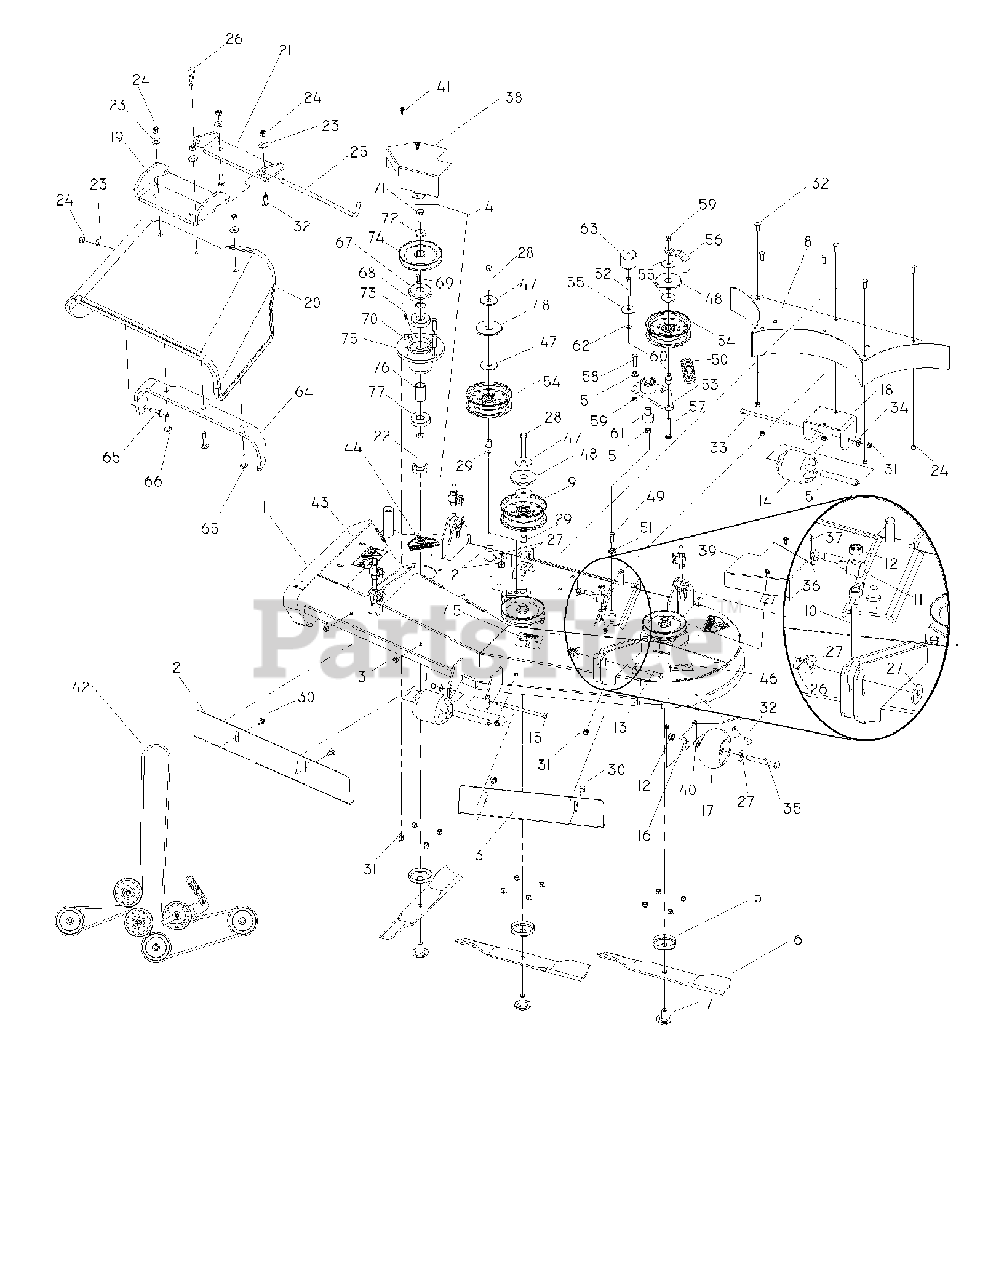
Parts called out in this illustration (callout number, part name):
1	DECK W/DECAL 52 KODIAK
2	BLOW-BY BAFFLE 52` LH
3	BLOW-BY BAFFLE 52` RH
4	SPINDLE ASM.
5	TRASH GUARD
6	BLD 52HFS HI LIFT FUS
7	BLADE BOLT/WASHER
8	W-BAFFLE WLDT.
9	IDLER PULLEY (TALL)
10	BOLT, EYE
12	NUT 1/2-13 HEX NYLOC ZD
13	CLEVIS PIN 1/2X1-3/4LG
14	ROLLER 3-3/4 DIA. X 4-1
15	BUSHING
16	BRACKET
17	GAUGE WHEEL
18	REAR CENTER ROLLER BKT 52 CLK
19	PIVOT BRKT RUBBER CHUTE
20	CHUTE, RUBBER DISCHARGE 52"
21	PIVOT BRACKET - DECK
22	SHAFT SHORT
23	WASHER 5/16 FLAT
24	NUT 5/16 NYLOC
25	DEFLECTOR PIN
26	PIN, COTTER 1 3/4
27	WASH USS FLAT 1/2
28	SCREW, 1/2C X 3 HEX CAP
29	SPACER - IDLER
30	RHSNB 3/8-16 X 3/4 GR5 ZD
31	NUT 3/8-16 NYLOC
32	RHSSNB 5/16C X 1.0
33	3/8-16 X 6-1/2 HHB GR8
34	WASHER 3/8 FLAT
35	HCS 1/2-13 X 4 GR 5 ZD
36	WASHER 1/2" FLAT
37	PIN COTTER 1/8 X 1 ZD
38	PULLEY GUARD RH BLACK
39	PULLEY GUARD 52 LH BLACK
40	NUT HEX 1/2
41	SCREW, TAP & DR #12-14 X 3/4
42	BELT-DECK, 52
43	DECAL, EURO SEVERING
44	DECAL, CPSC
45	DECAL, BELT ROUTING (18656)
46	DECAL, 52"
47	ISOLATOR WASHER
48	TOP DUST CAP
49	HCS 3/8C X 1
50	DECK SPRING
51	NUT 3/8C WHIZ
52	HCS 3/8C X 2 1/2
53	ARM-IDLER W/BRG
54	IDLER PULLEY
55	WASHER, 3/8 SPEC
56	GUIDE, BELT
57	RHSNB 3/8-16 X 2.75
58	HCS 3/8-16 X 1-1/2
59	NUT 3/8-16 HEX JAM
60	BUSHING, IDLER
61	PIVOT, BEARING
62	WASHER 3/8 SAE FLAT
63	CAP, VINYL
64	BRACKET, REINF - CHUTE
65	BOLT, CARRIAGE 5/16X1-1/4
66	RHSNB 5/16-18 X 1-1/2 GR 5 ZD
67	TRASH GUARD
68	HUB PULLEY SPACER
69	KEY - 1/4 X .88
70	HCS 3/8C X 1 1/2
71	1/2-20 UNF X 1 1/4 HHBLT
72	WASHER .525 X 1.375 X .25
73	ZERK, 3/16, DRIVE IN
74	METRIC PULLEY
75	DECK HUB MACHINED
77	BEARING - 6305 - 2RS
